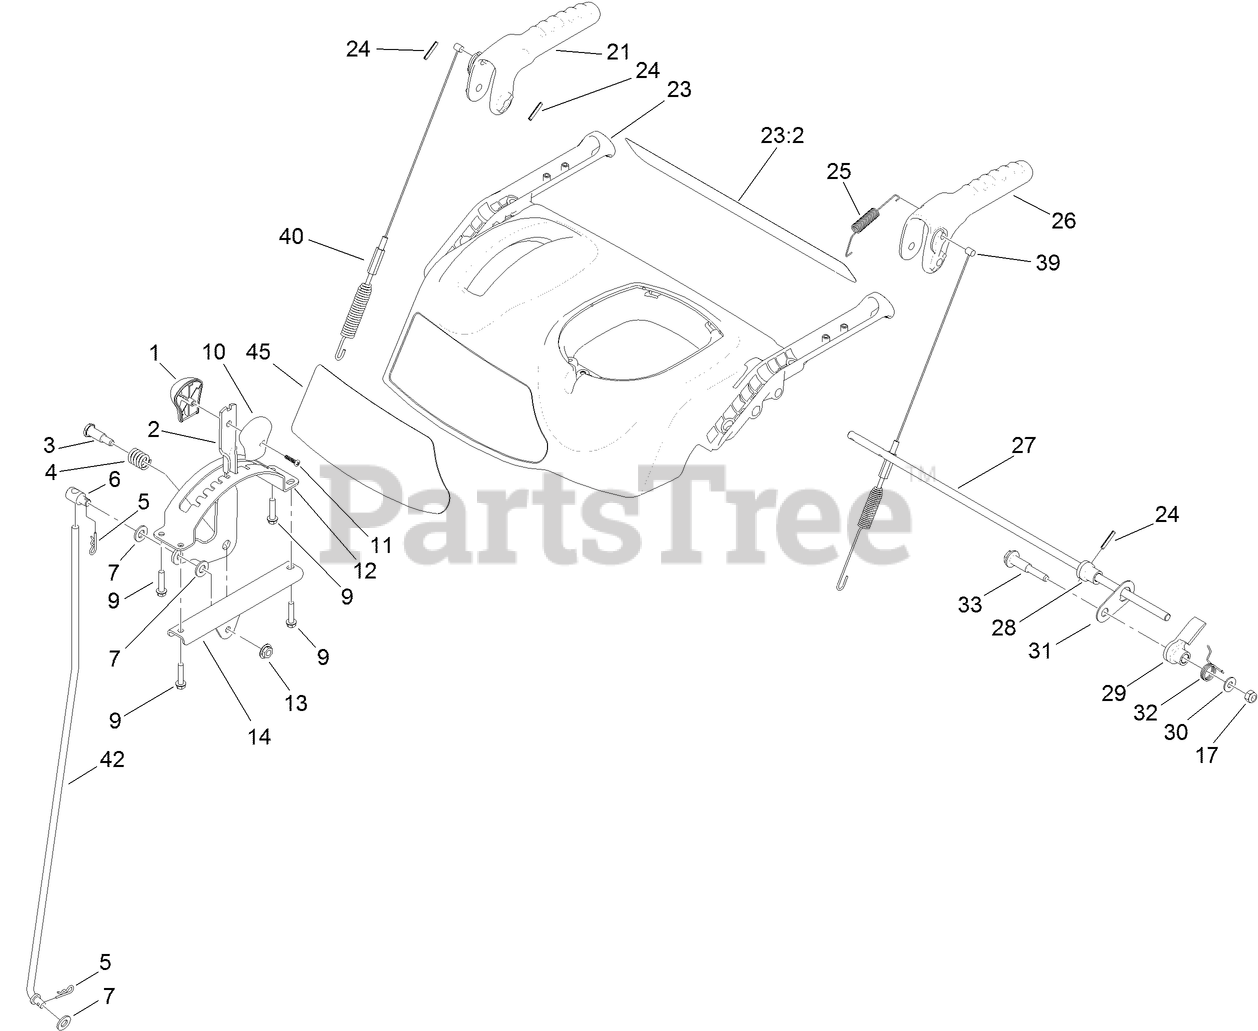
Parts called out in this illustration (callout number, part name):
1	KNOB-SHIFT, RH
2	SELECTOR-SPEED
3	SCREW-SHOULDER
6	TRUNNION-ROD
7	WASHER-FLAT
9	SCREW-PLASTITE
10	KNOB-SHIFT, LH
11	SCREW-PPH
12	GUIDE-SELECTOR, SPEED
13	NUT-HF
14	MOUNT-SELECTOR, SPEED
17	NUT-LOCK, NI
21	LEVER-AUGER
23	CONTROL PANEL ASM
23:2	DECAL-PANEL, CONTROL
24	PIN-SPRING
25	SPRING-TENSION
26	LEVER-TRACTION
27	ROD-LOCKOUT
28	CAM-LOCKOUT
29	LATCH-LOCKOUT
30	WASHER-FLAT
31	LINK-LOCKOUT
32	SPRING-TORSION
39	CABLE-TRACTION
40	CABLE-AUGER
